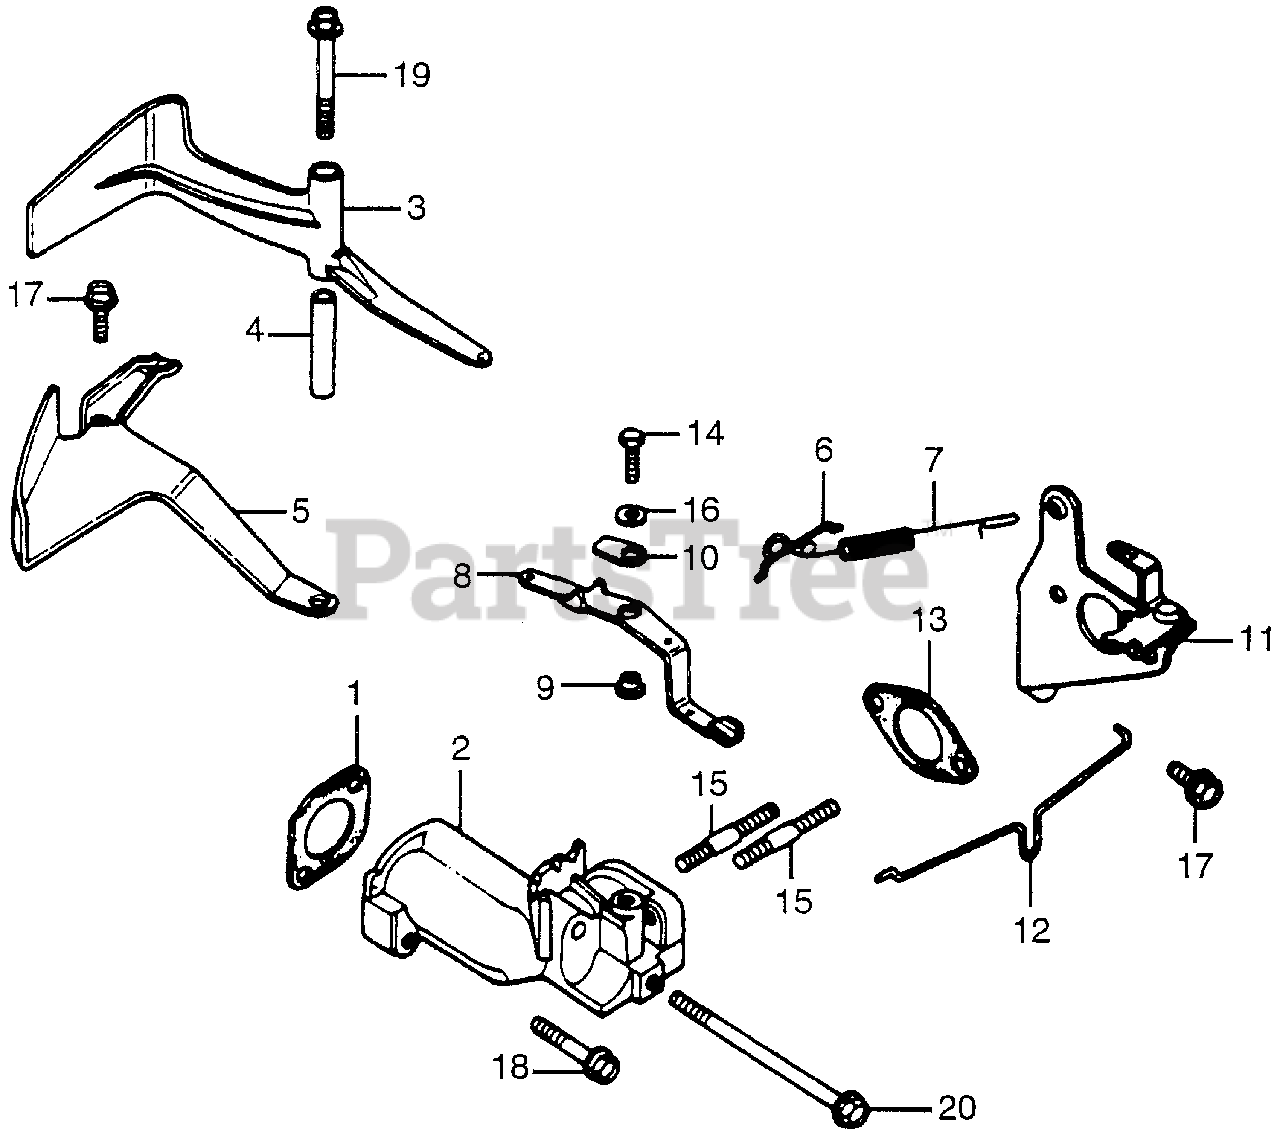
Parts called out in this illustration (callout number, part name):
1	GASKET, ELBOW
2	ELBOW, CARBURETOR (NOT AVAILABLE)
3	FLUTTER, GOVERNOR
4	COLLAR, FLUTTER
5	GUIDE, WIND
6	ROD, GOVERNOR (NOT AVAILABLE)
7	SPRING, GOVERNOR
8	LEVER, CONTROL
9	COLLAR, LEVER SETTING
10	SPRING, LEVER SETTING (NOT AVAILABLE)
11	LEVER, CHOKE (NOT AVAILABLE)
12	ROD, CHOKE (NOT AVAILABLE)
13	GASKET, AIR CLEANER ELBOW
14	BOLT, HEX. (5X14)
15	BOLT, STUD (6X37)
15	BOLT 2, STUD (6X25)
16	WASHER, PLAIN (5MM)
17	BOLT, FLANGE (6X12)
18	BOLT, FLANGE (6X25)
19	BOLT, FLANGE (6X45)
20	BOLT, FLANGE (6X70)
